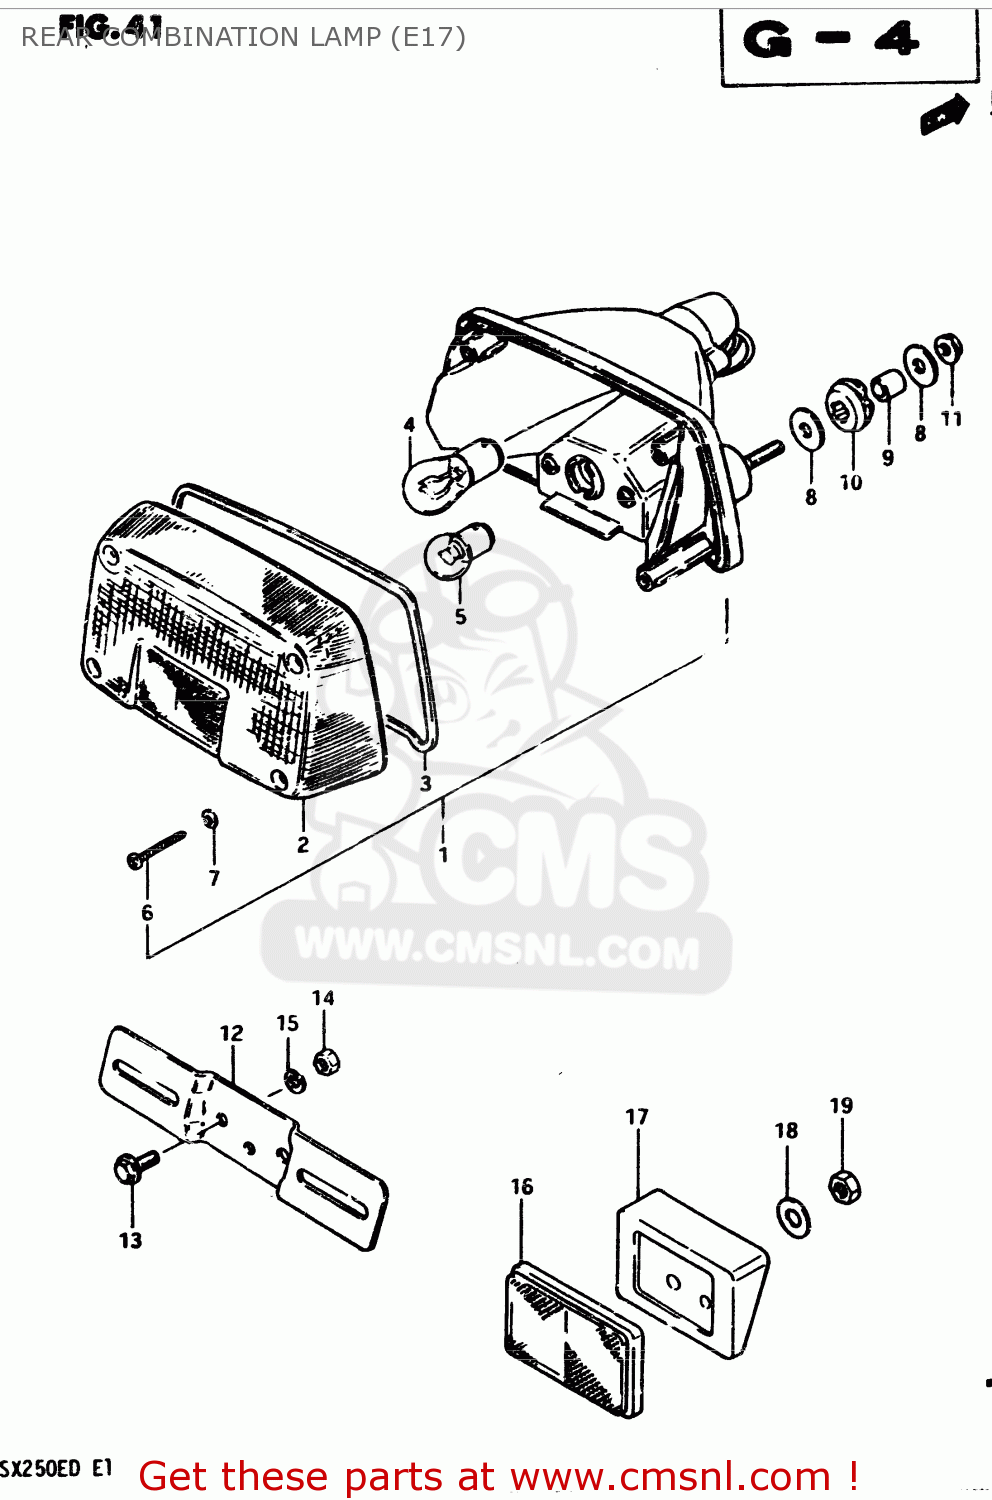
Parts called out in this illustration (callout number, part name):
1	LAMP ASSY, REAR COMBINATION
2	LENS
3	GASKET
4	BULB(12V21/5W)
5	BULB
6	SCREW
7	GASKET (NAS)
8	WASHER
9	SPACER (6.8X10X11.5)
10	CUSHION
11	NUT 6MM
12	BRACKET, LICENSE PLATE
13	BOLT
14	NUT
15	LOCK WASHER
16	REFLEX REFLECTOR,RR
17	SPACER
18	WASHER(5.2X16X1)
19	NUT
